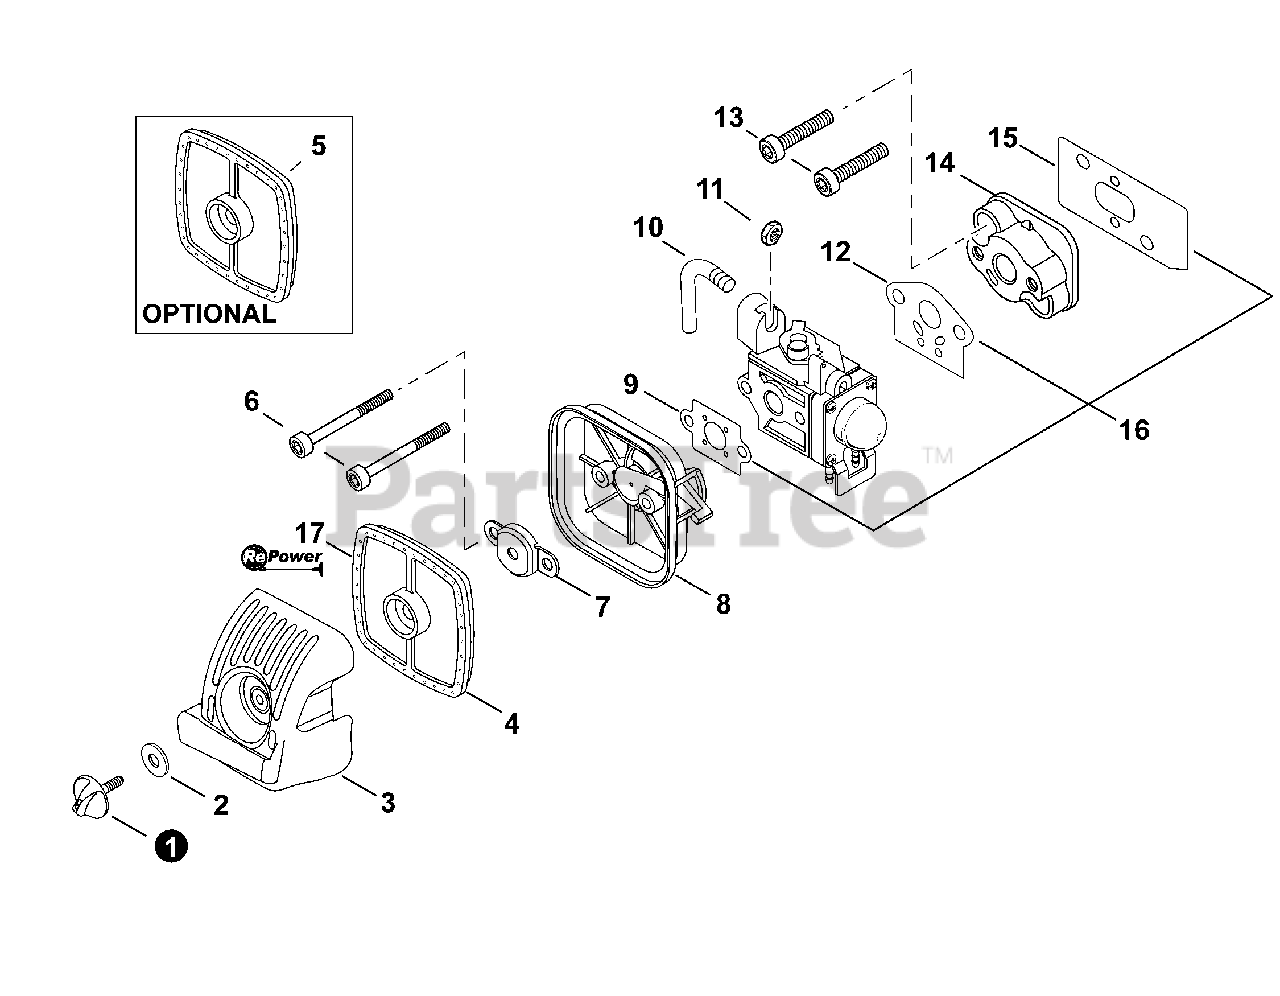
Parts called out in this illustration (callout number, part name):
1	THUMBSCREW
2	WASHER 5.5×16×0.8
3	COVER, AIR FILTER
4	FILTER, AIR - DOUBLE LAYER
5	FILTER, AIR - SINGLE LAYER
6	BOLT 5×60
7	PLATE, PREVENT
8	CASE ASSY, AIR FILTER
9	GASKET, INTAKE
10	ADJUSTER, THROTTLE CABLE
11	NUT 3N-7
12	GASKET, CARBURETOR
13	BOLT 5×25
14	INSULATOR, INTAKE
15	GASKET, INTAKE
16	GASKET KIT
17	TUNE-UP KIT - REPOWER
